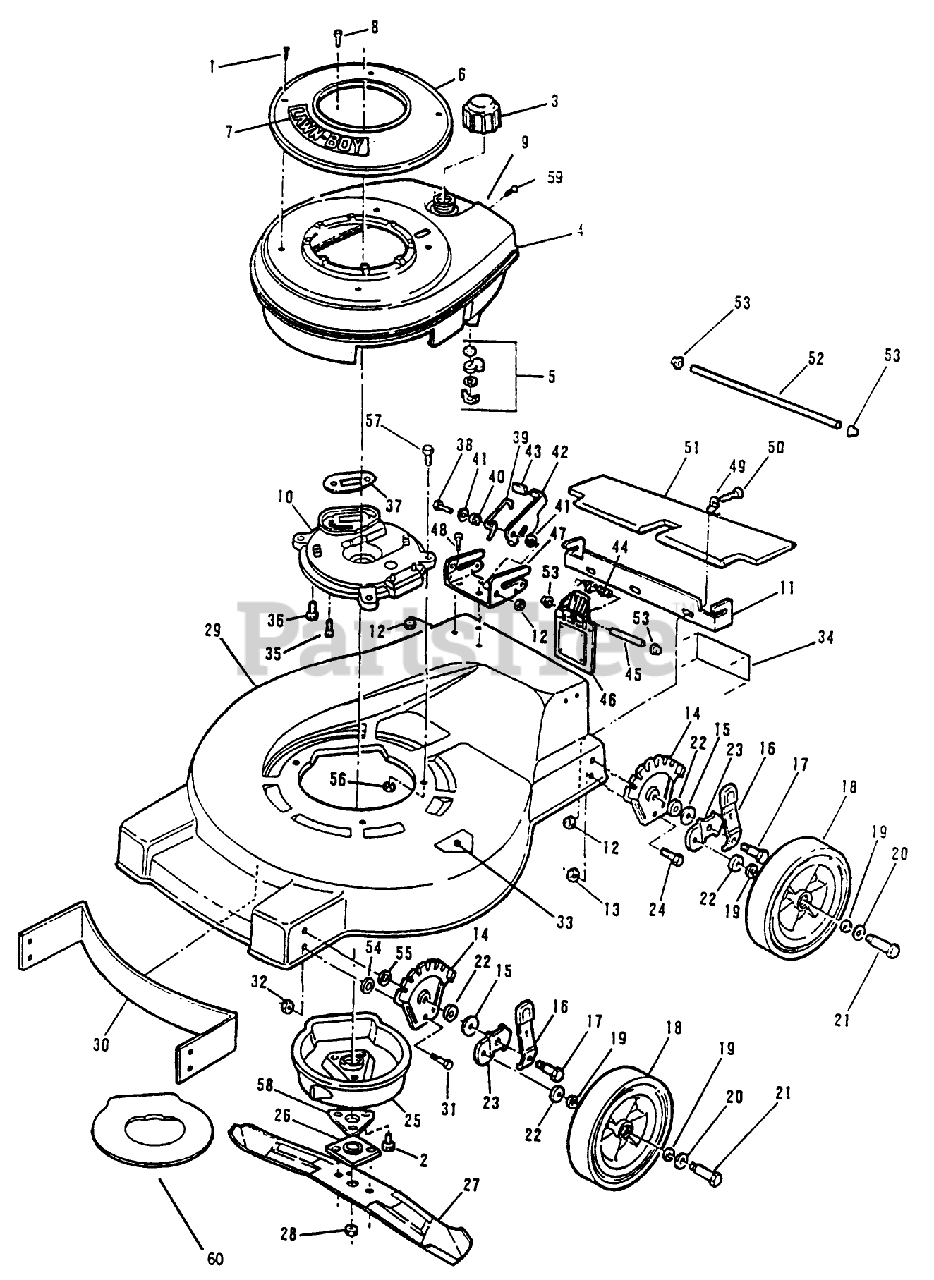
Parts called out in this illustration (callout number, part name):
1	SCREW - SELF TAPPING
2	SCREW
3	FUEL CAP & INSERT
4	SHROUD,TANK&VAL
5	SHUT OFF VALVE KIT
8	SCREW SEMS SM
12	LOCKNUT E
13	LOCKNUT
15	WASHER
16	KNOB&SPRING FORMCO
17	BOLT
19	WASHER
20	SPACER
21	BOLT WHEEL
22	WASHER WROUGHT
26	PLATE AND COLLAR ASM
28	NUT-BLADE
32	LOCKNUT
35	SCREW V
39	SPRING
43	KNOB (S&R)
44	SPRING ASOC
45	ROD ROCK/HDWE
51	T/SHIELD SM&P
54	WASHER
55	WASHER
56	NUT-LOCK F
57	SCREW-HH
58	SUPPORT F
59	SCREW S
60	BAFFLE,MUFFLER S
